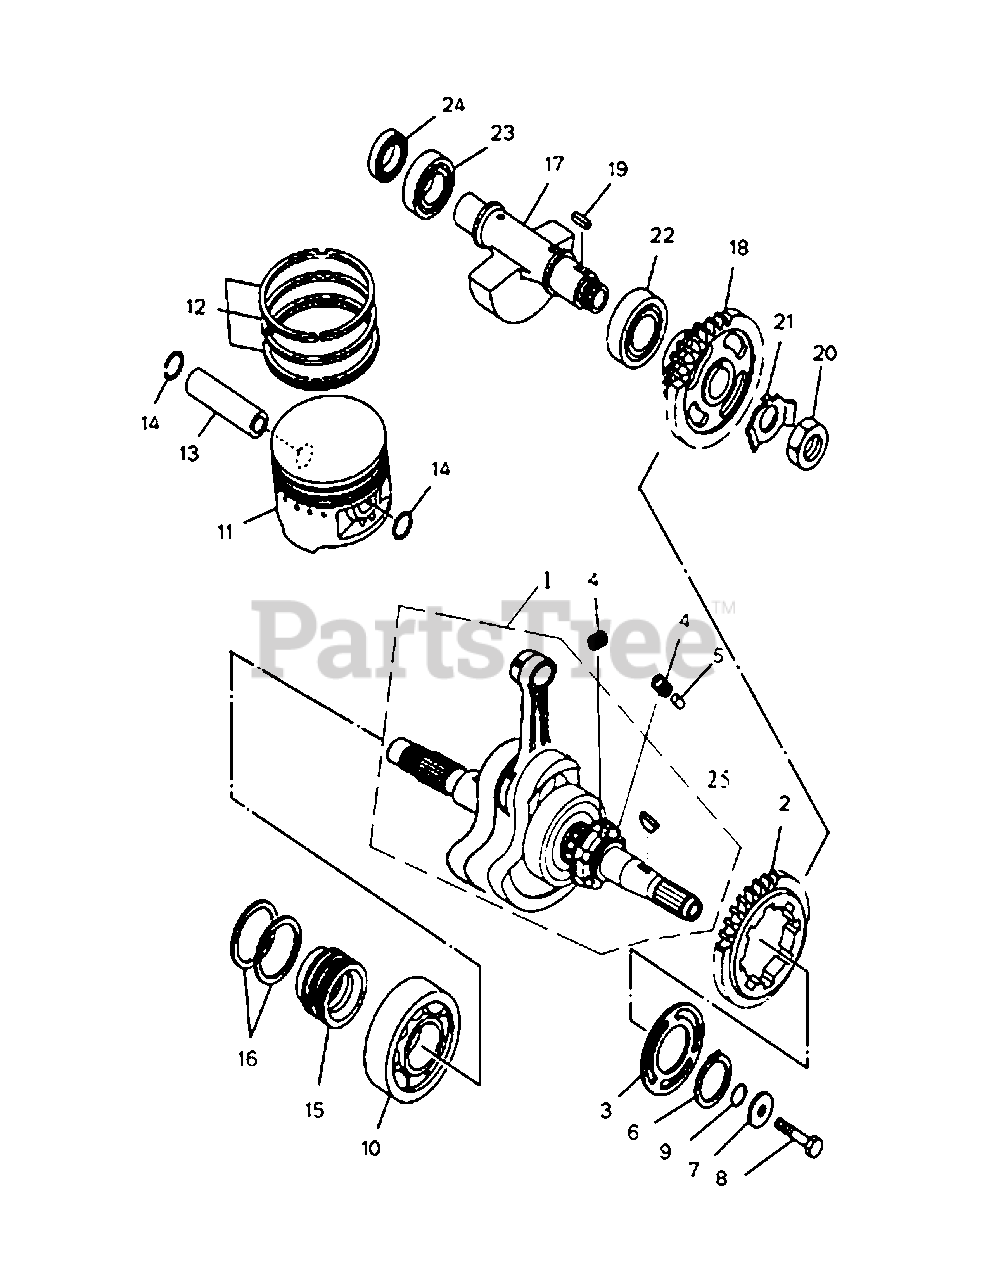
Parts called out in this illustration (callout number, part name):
1	CONNECTING ROD-COMP CRANK
2	Gear-Balanced Initiative
3	Clamper Plate-Intiative Gear
4	Spring-Buffer
8	Hexagon Head Bolt M10X1.25X40
12	Piston Ring-Comp
14	Circlip:Piston Pin
15	Seal-Ring Sheath
17	Shaft Asm-Balanced
18	Driven Gear-Balance Shft Asm
21	Thrust Washer
25	Key-Semi Circle
